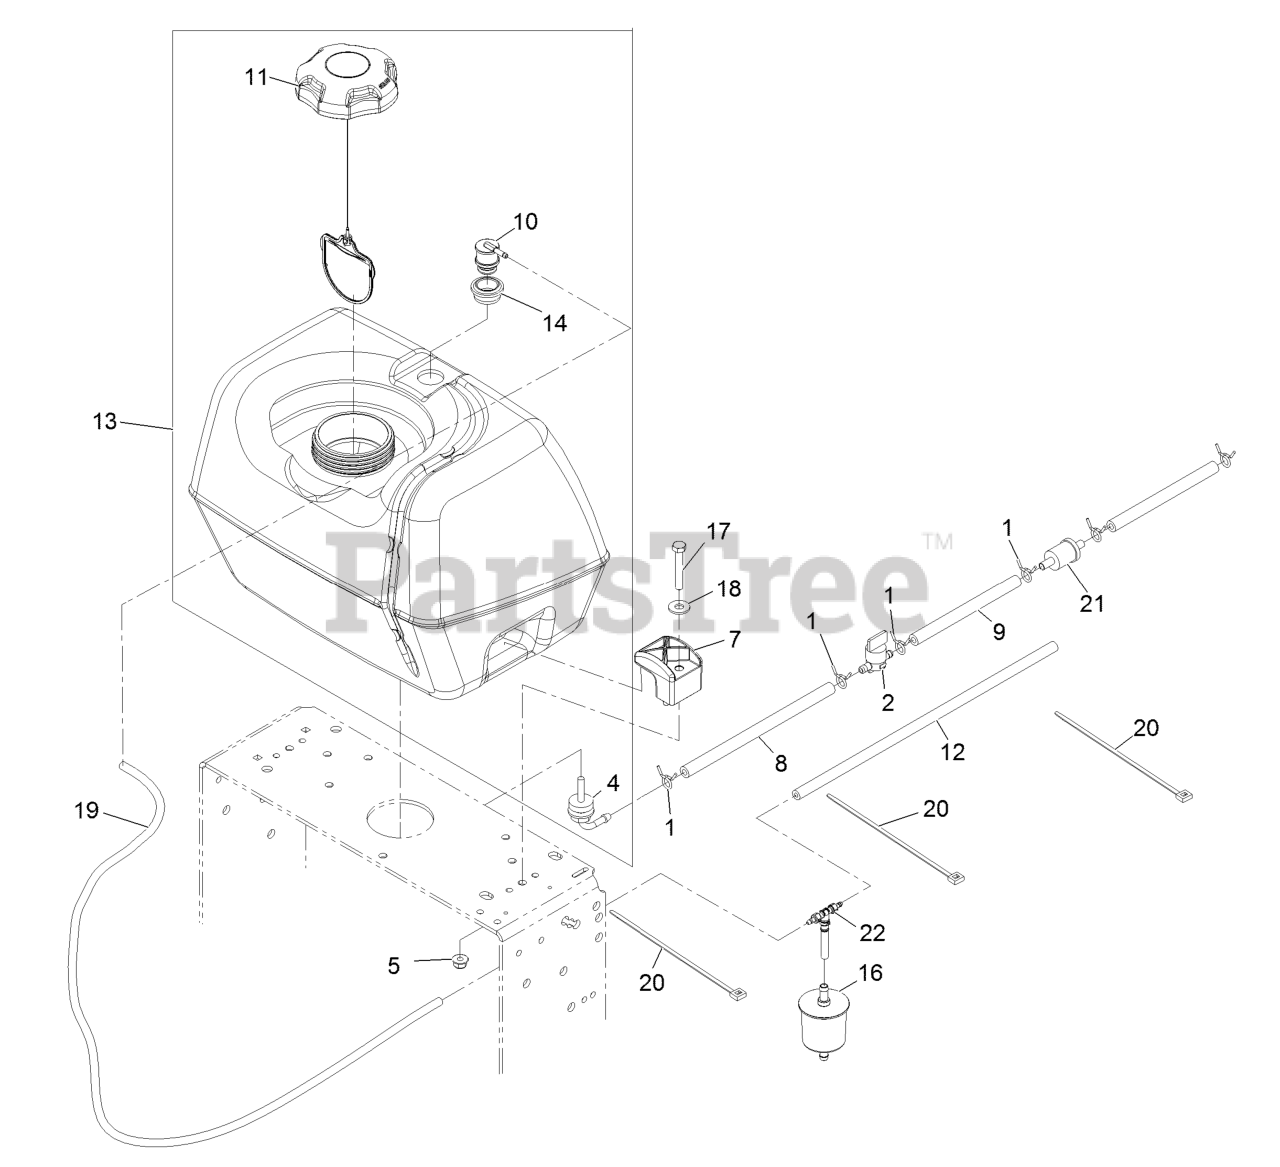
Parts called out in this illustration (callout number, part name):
1	CLAMP-HOSE
2	VALVE-FUEL
4	FITTING-FUEL, BULKHEAD
5	NUT-HF, NI
8	HOSE-FUEL
9	HOSE-FUEL
10	VALVE-VENT, FUEL
12	HOSE-FUEL
13	ASM, FUEL TANK
14	GROMMET
16	FILTER-FUEL
17	SCREW-HH
18	WASHER-FLAT
19	HOSE-EMISSIONS
20	TIE-PLASTIC
21	Pn 41019-1055 Filter W/6in Fuel Line
22	TEE AND CHECK
